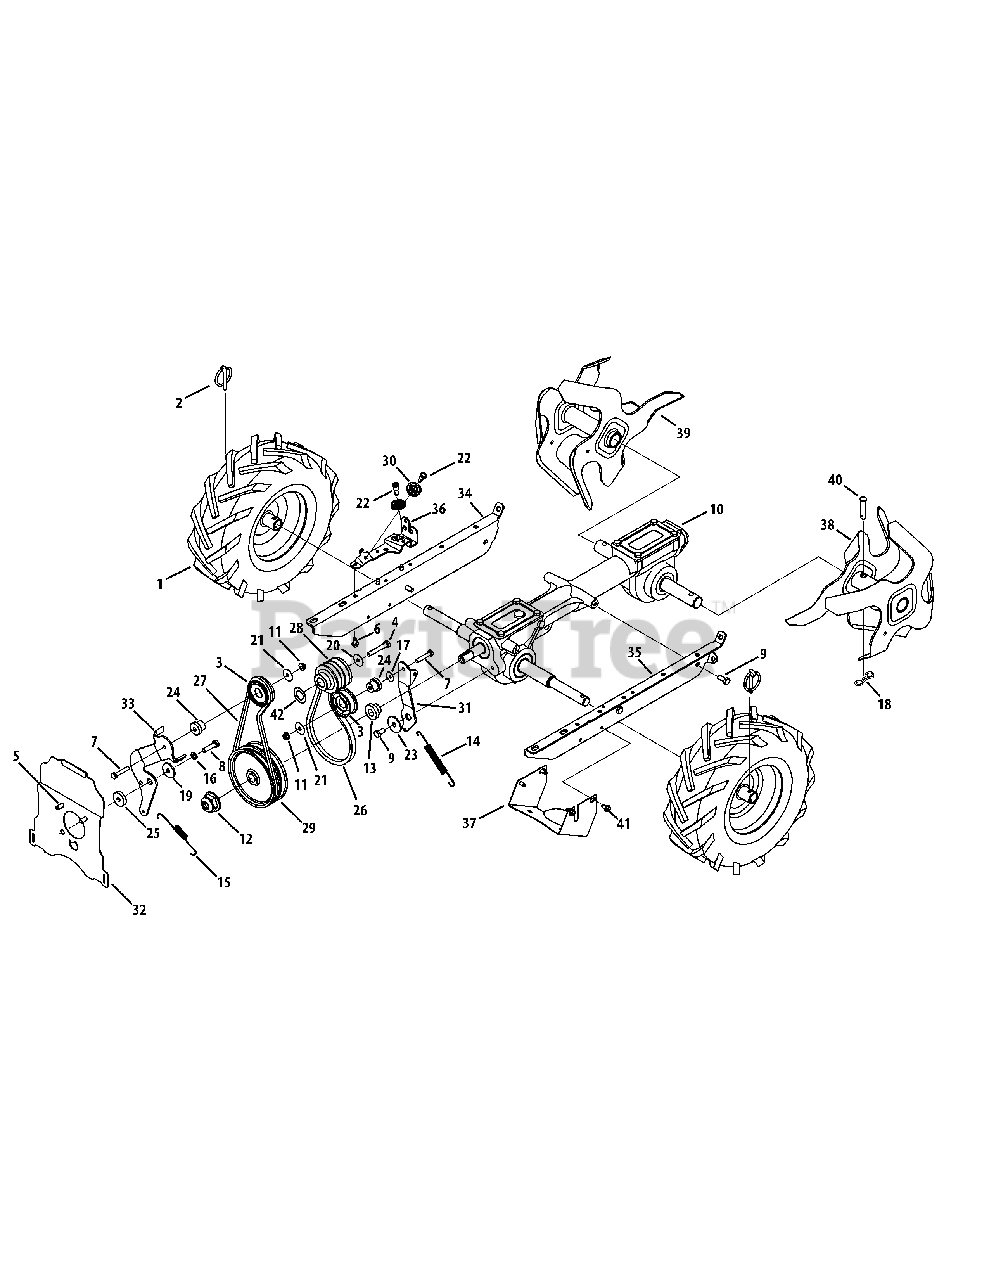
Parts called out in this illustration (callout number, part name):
1	Complete Wheel Assy., 13 x 5 x 6
2	Click Pin
3	Idler Pulley Assembly
4	Hex Head Screw, 3/8-24 x 2.25
5	Hex Head Screw, 5/16-24 x .625
6	Self Tapping Screw, 1/4-20 x .500
7	Hex Head Screw, 1/4-20 x 1.50
8	Hex Head Screw, 5/16-18 x 1.25
9	Hex Head Screw, 5/16-18 x .75, Patch
10	Transmission Assembly
11	Nylon Hex Lock Nut, 1/4-20
12	Nut, 9/16-18, Flange Lock
13	Hub, 5/8 Spline
14	Extension Spring, .480 OD X 5.00 LG
15	Extension Spring, PTO
16	Lock Washer, 5/16
17	Washer, .28 x .74 x .063
18	Internal Cotter Pin
19	Flat Washer, .330 X 1.25 X .120
20	Bell Washer, .396 x 1.140 x .095
21	Flat Washer, .265 x 1.0 x .030
22	Shoulder Screw, .342 x .335 1/4-28
23	Pivot Idler Spacer
24	Shoulder Spacer, .260 x .785 x .538
25	Pivot Idler Spacer
26	V-Belt, 4L x 25.375 Long
27	V-Belt, 3L x 29.125 Long
28	Engine Pulley
29	Transmission Pulley
30	Cable Roller
31	Idler Bracket, Forward
32	Cover Plate
33	Idler Bracket, Reverse
34	Mounting Frame, RH
35	Mounting Frame, LH
36	Pulley Bracket
37	Pulley Shield
38	Tine Assembly, LH
39	Tine Assembly, RH
40	Clevis Pin, .375 x 1.75
41	Hex Washer Screw, 1/4-14 x .625
42	Flat Washer, .760 x 1.500 x .120
